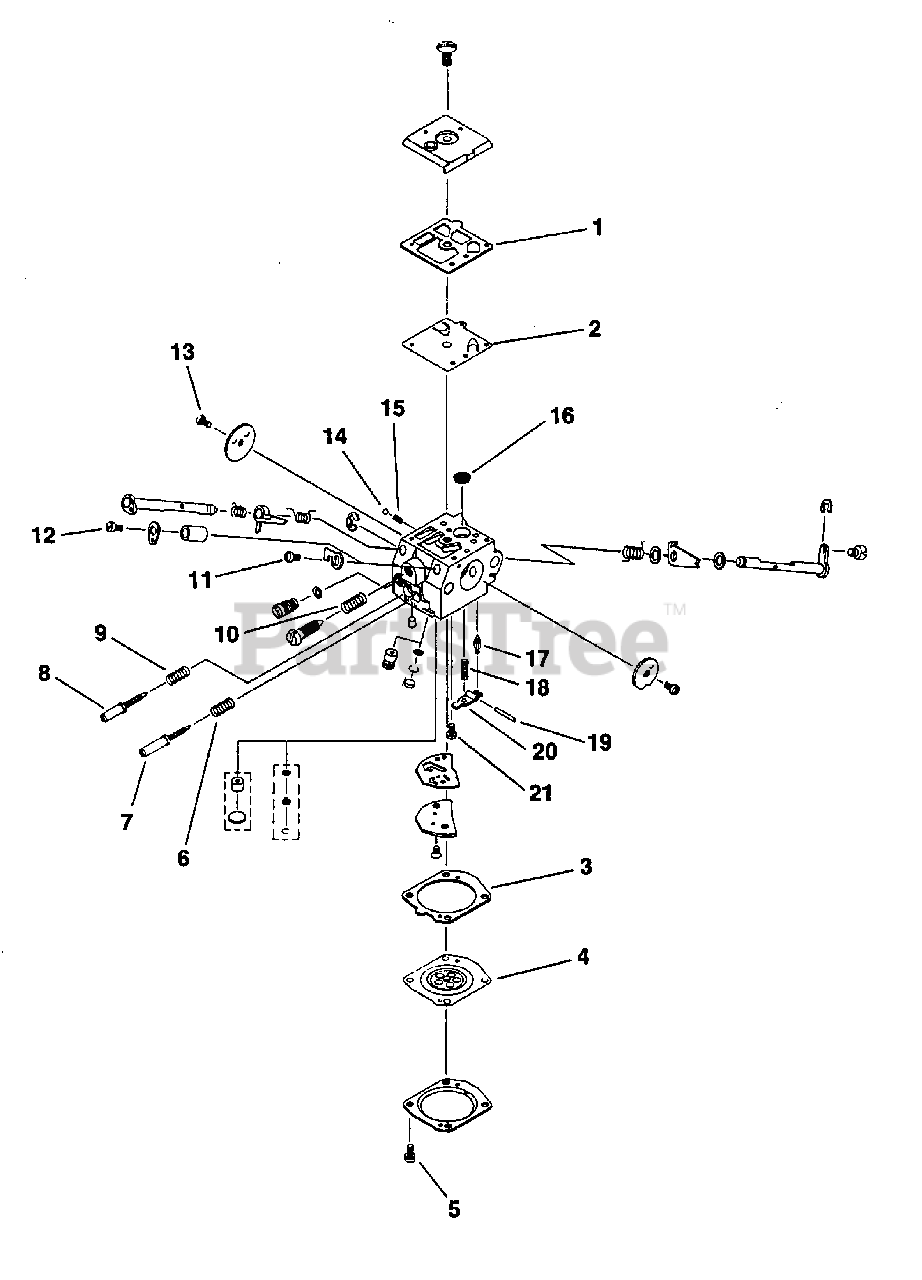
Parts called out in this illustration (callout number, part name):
1	Repair Kit
2	Repair Kit
3	Repair Kit
4	Repair Kit
5	Repair Kit
6	Repair Kit
7	Repair Kit
8	Repair Kit
9	Repair Kit
10	Repair Kit
11	Repair Kit
12	Repair Kit
13	Repair Kit
14	Repair Kit
15	Repair Kit
16	Repair Kit
17	Repair Kit
18	Repair Kit
19	Repair Kit
20	Repair Kit
21	Repair Kit
